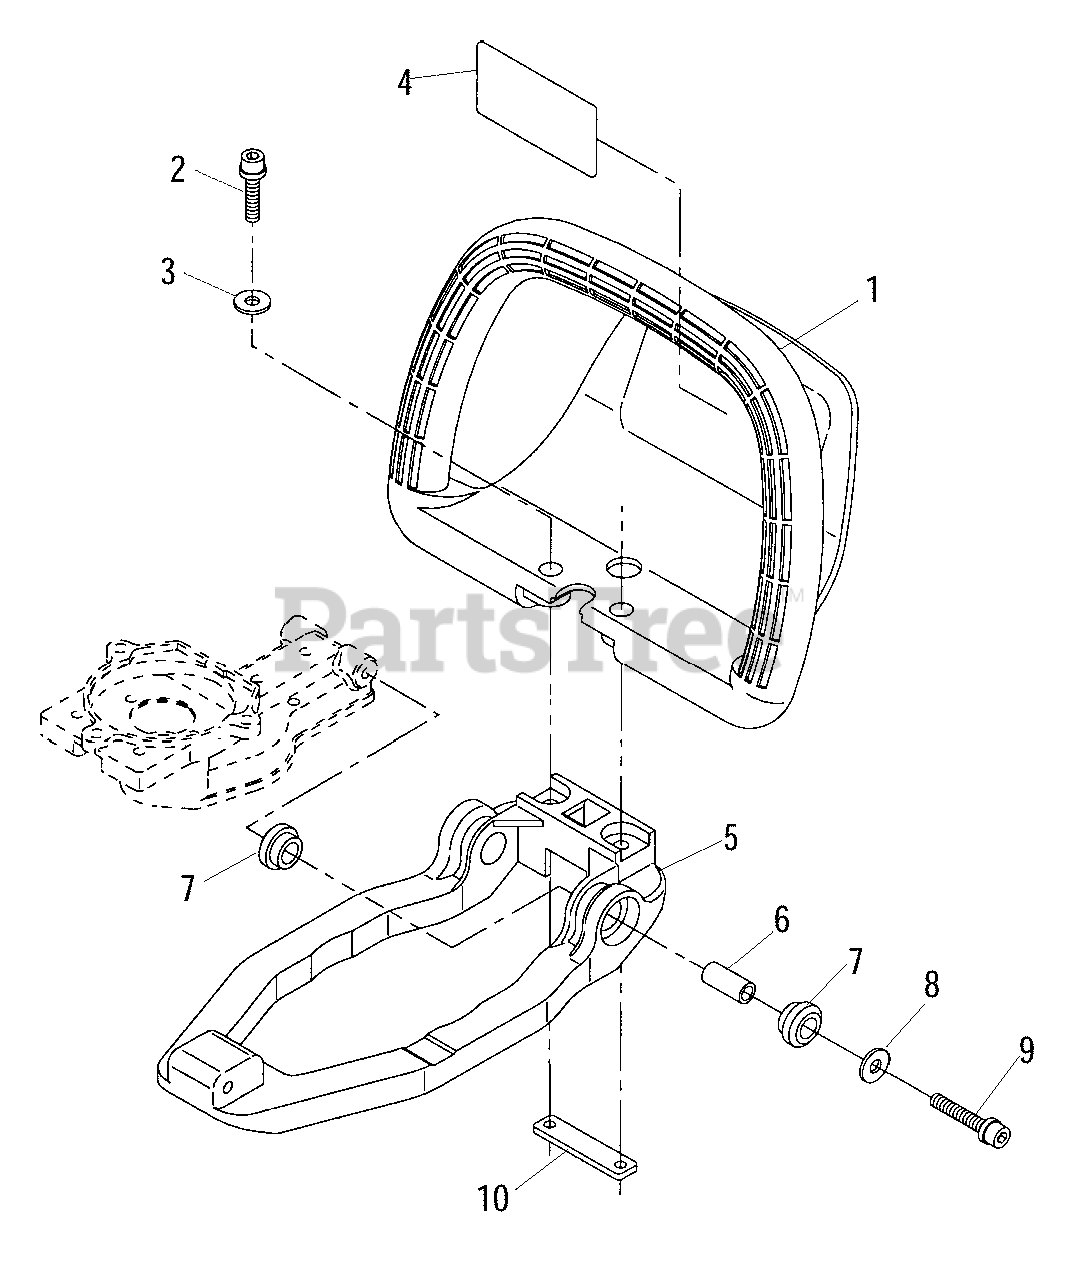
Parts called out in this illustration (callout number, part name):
1	HANDLE, FRONT
2	BOLT M6×25
3	WASHER Ø16ר6.5×1.6 MM
4	LABEL, CAUTION
5	BASE
6	COLLAR 6
7	CUSHION
8	WASHER Ø16ר6.5×1.6 MM
9	BOLT M6×35
